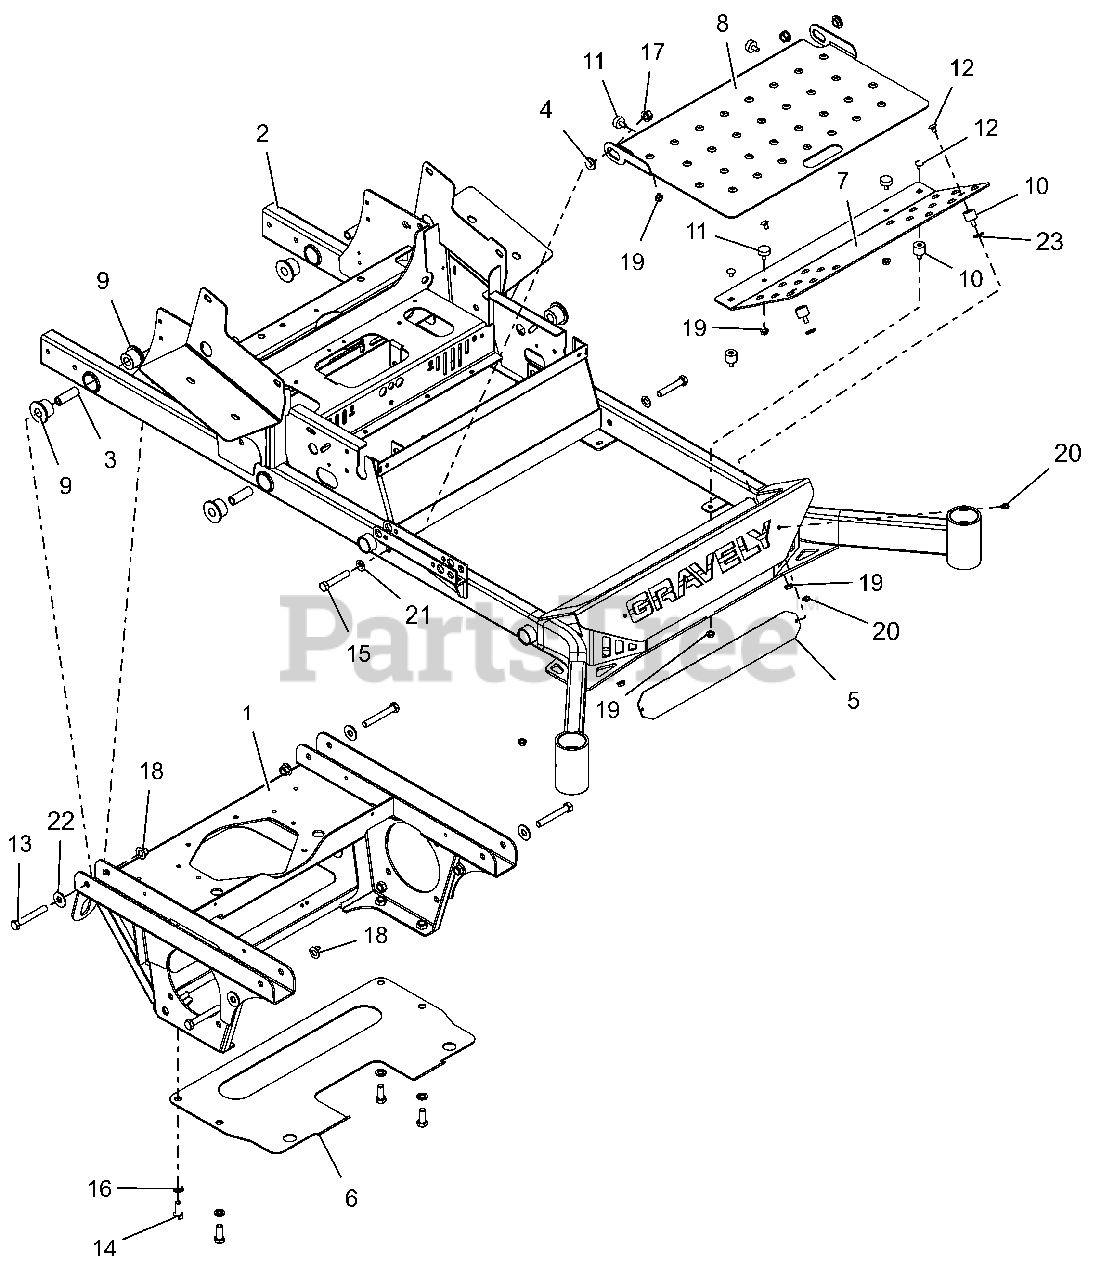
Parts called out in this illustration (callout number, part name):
1	PT200/400 AXLE/ENG FRM WMT-RED
2	72" PT200/400 FRAME W/DECALS
3	BSHG-SLV .50X.75X2.23
4	BSHG-FLG .515X.750X.310X1.120
5	BUMPER LOGO BACKING PLATE -BLK
6	PLATE-TRANSMISSION SKID
7	FOOTREST W/ SAFTEY DECALS
8	INSPECTION PANEL W/SAFE DECAL
9	BSHG-FLG .75X1.51X1.13X2.0 URE
10	BUMPER,STUD MNTD W/FEMALE INSR
11	BUMPER, RUBBER
12	@BLT-RDHDSQNK .31-18X.50 G5YZ
13	@BLT-HEX .50-13X3.50 GR5 YWZC
14	@BLT-HEX .50-13X1.25 GR5 YWZC
15	@BLT-HEX .50-13X2.75 GR5 YWZC
16	@WSHR-LK .50X.125 REG YWZC
17	NUT-LK-CTR-FLG .50-13 YWZC
18	@NUT-LK-NYL-FLG .50-13 YWZC
19	@NUT-SPNLK-FLG .312-18 YWZC
20	SCR-TAP .25-20X.50 HWH TR YWZ
21	WSHR-FL-STL.531X1.00X.063 YWZC
22	@WSHR-FL-STL.563X1.38X.109YWZC
23	@WSHR-FL-STL.38X.875X.083 YWZC
